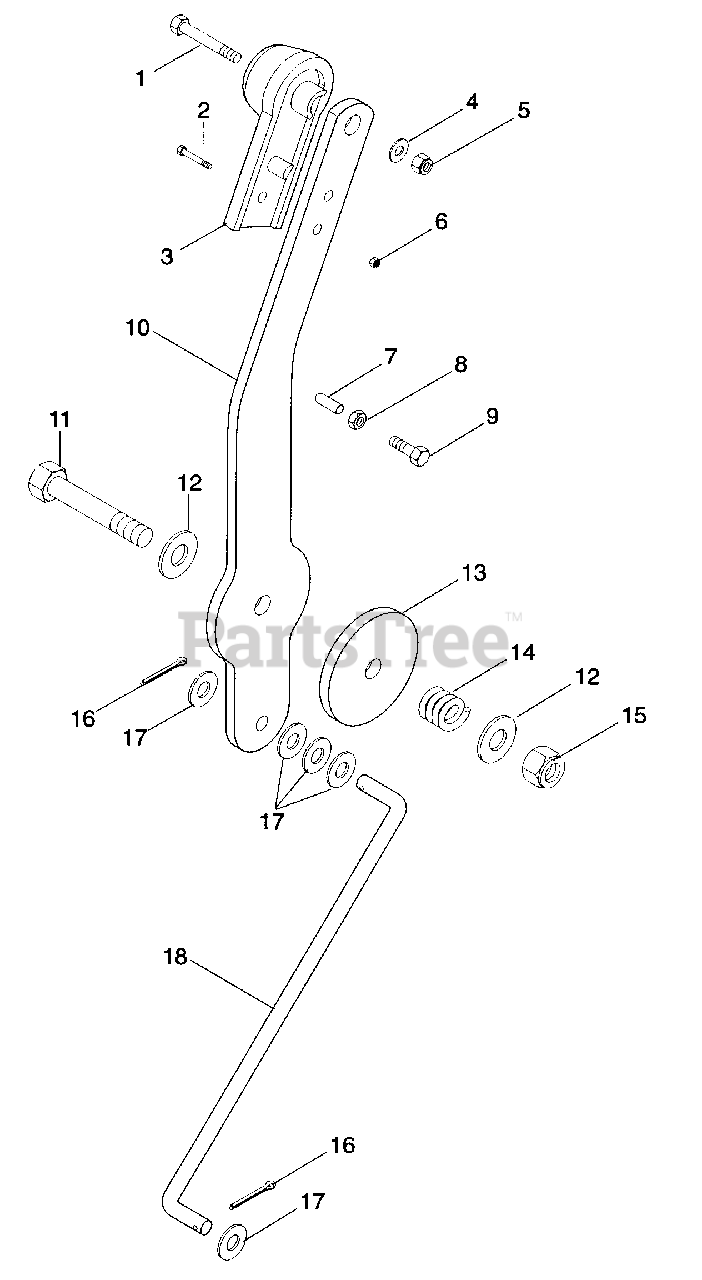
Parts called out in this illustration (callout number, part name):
1	Bolt-Hex .25-20 x 1.50 Grade 5
2	Screw-Machine 6-32 x .625
3	Knob, Hand Control
4	Washer-Flat-Steel .281 x .625 x .065
5	Nut-Locking-Nylon .250-20 Grade 2
6	Nut-Locking-Machine 6-32 w/Insert
7	Cap
8	Nut-Hex .250-20 Grade 2
9	Bolt-Hex .25-20 x .75 Grade 5
10	Lever, Speed Control
11	Bolt-Hex .50-13 x 2.50 Grade 5
12	Washer-Flat-Steel .531 x 1.062 x .095
13	Disc, Friction Material
14	Spring-Compression .125 x .78 x 1.00
15	Nut-Locking-Nylon .50-13 Grade 5
16	Pin-Cotter .09 x 1.0
17	Washer-Flat-Steel .406 x .812 x .065
18	Rod, Speed Control
